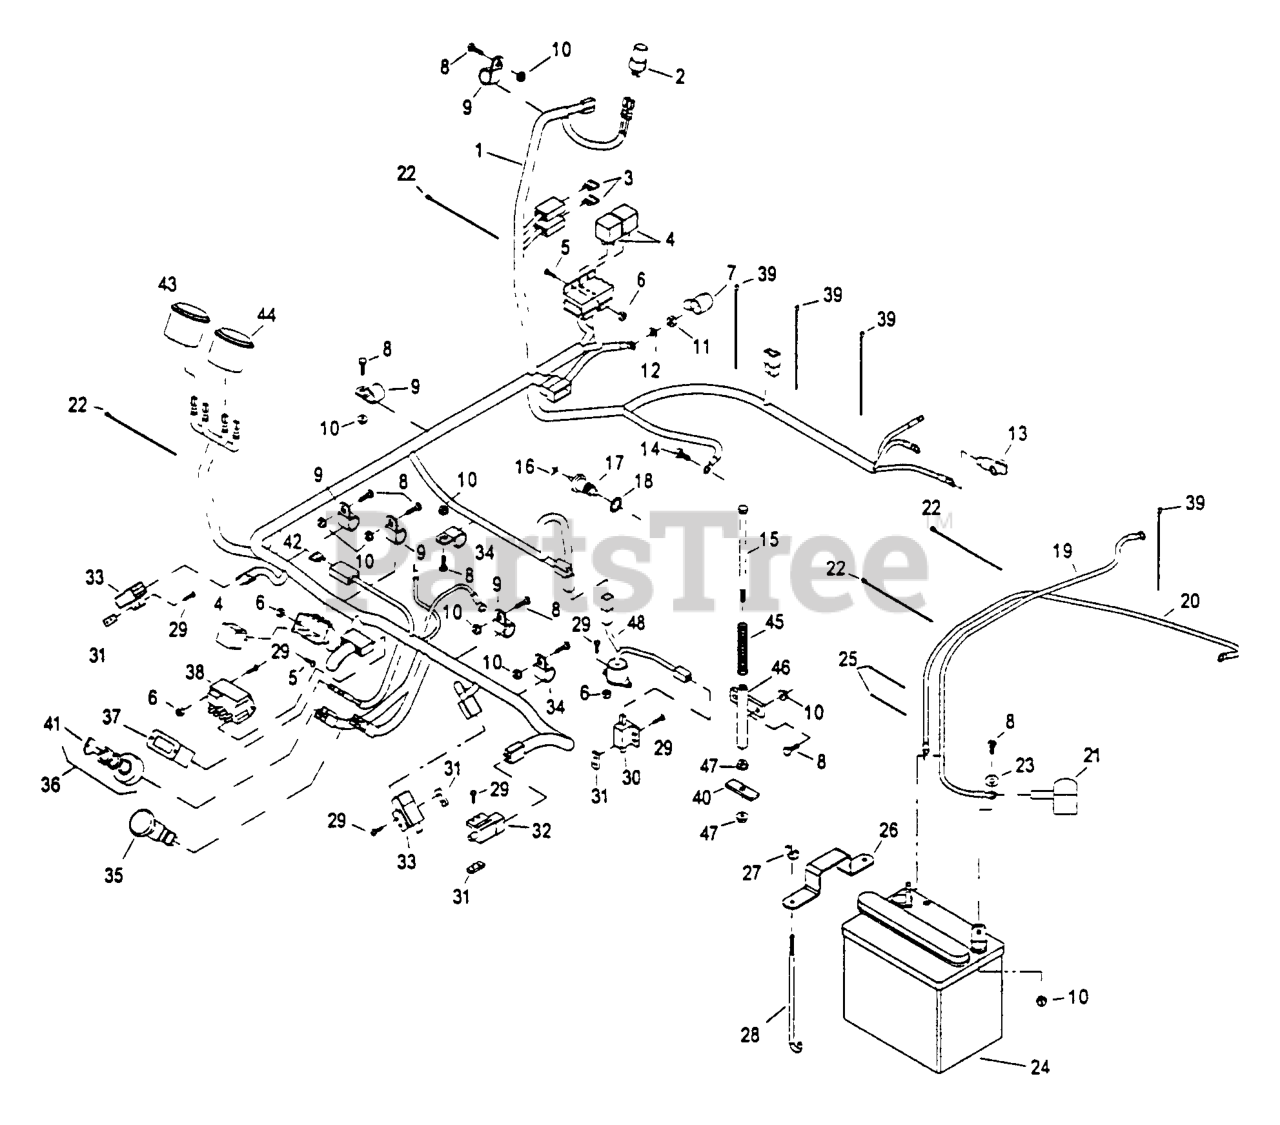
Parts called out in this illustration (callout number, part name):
2	SWITCH-THERMAL, FAN
3	FUSE-BLADE TYPE, 30 AMP
7	INSULATOR-SOLENOID
9	CLIP-LOOM
12	WASHER-LOCK
13	CAP-INSULATOR, RED
14	Screw, Hex M8-1.25x16
15	SCREW-HH
17	SENDER UNIT-TEMPERATURE
18	WASHER-ALUMINUM
20	WIRE-GROUND
22	TIE-PLASTIC
24	Battery 12v
25	TIE-CABLE
26	STRAP-HOLDDOWN
27	WINGNUT
28	BOLT-HOLDDOWN
30	SWITCH-CLOSED, NORMALLY
31	PLATE-TAPPED
32	SWITCH-BRAKE
34	CLIP-LOOM
36	SWITCH,IGNITION
37	METER-HOUR
38	MODULE,IGNITION INTRLOCK
39	TIE-PLASTIC
40	PLATE-SWITCH, SEAT
41	KEYS-IGNITION (SPARE PAIR
42	FUSE-BLADE TYPE, 20 AMP
43	GAUGE-VOLTMETER
44	GAUGE-TEMPERATURE
45	SPRING-SWITCH, SEAT
46	MOUNT-SPRING, SEAT
